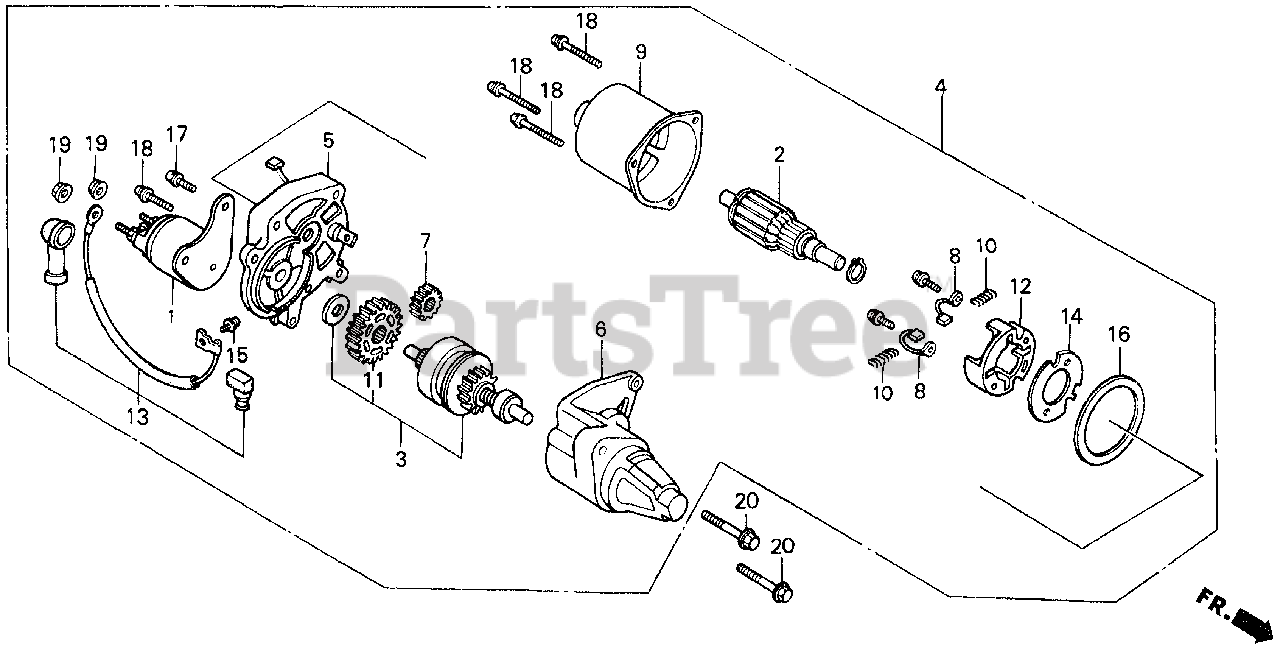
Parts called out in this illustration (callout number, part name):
1	CONTACTOR ASSY.
2	ARMATURE
3	CLUTCH, OVERRUNNING
4	MOTOR UNIT, STARTER
5	BRACKET, CENTER
6	BRACKET, FR.
7	GEAR, DRIVE PINION
8	BRUSH
9	YOKE
10	SPRING, BRUSH RETURN
11	GEAR, REDUCTION
12	HOLDER, BRUSH
13	WIRE, WATER COVER
14	INSULATOR
15	SCREW-WASHER (4X6)
16	GASKET
17	BOLT-WASHER (5X14)
17	SCREW-WASHER (5X14)
18	SCREW-WASHER (5X3)
19	NUT-WASHER (6MM)
20	BOLT, FLANGE (8X35)
